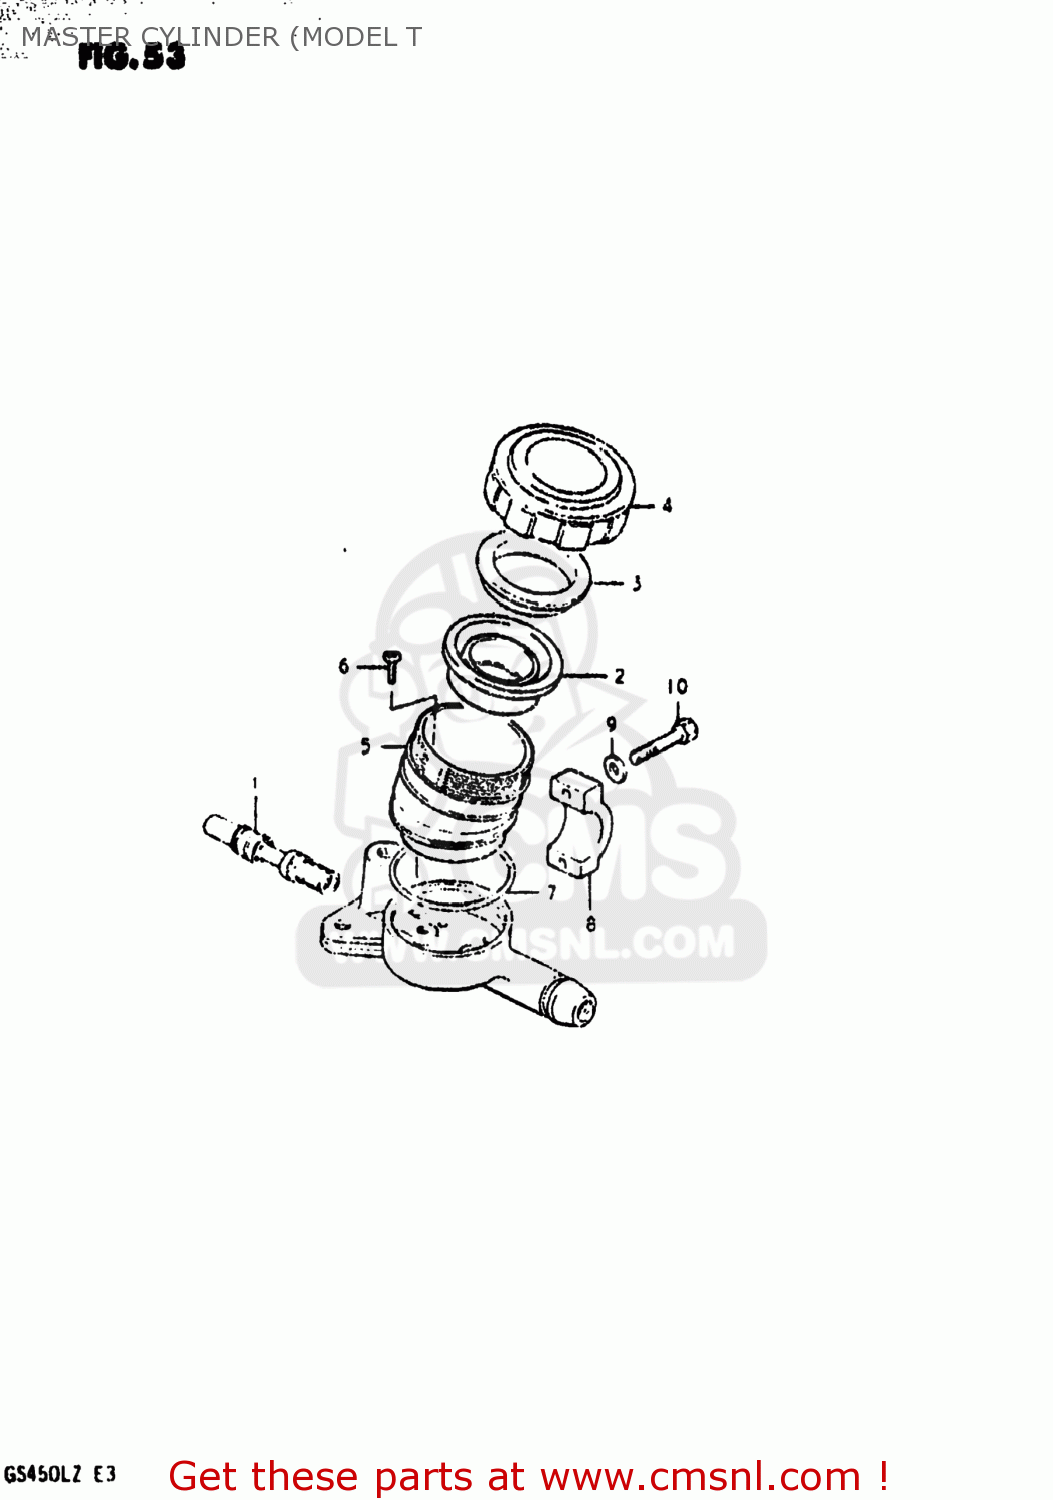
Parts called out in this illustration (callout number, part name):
1	PISTON & CUP SET
2	DIAPHRAGM
3	PLATE,DIAPHRAGM
4	CAP
5	RESERVOIR
6	SCREW,MASTER CYLINDER
7	O RING
8	HOLDER,MASTER CYLINDER
9	WASHER
10	BOLT
